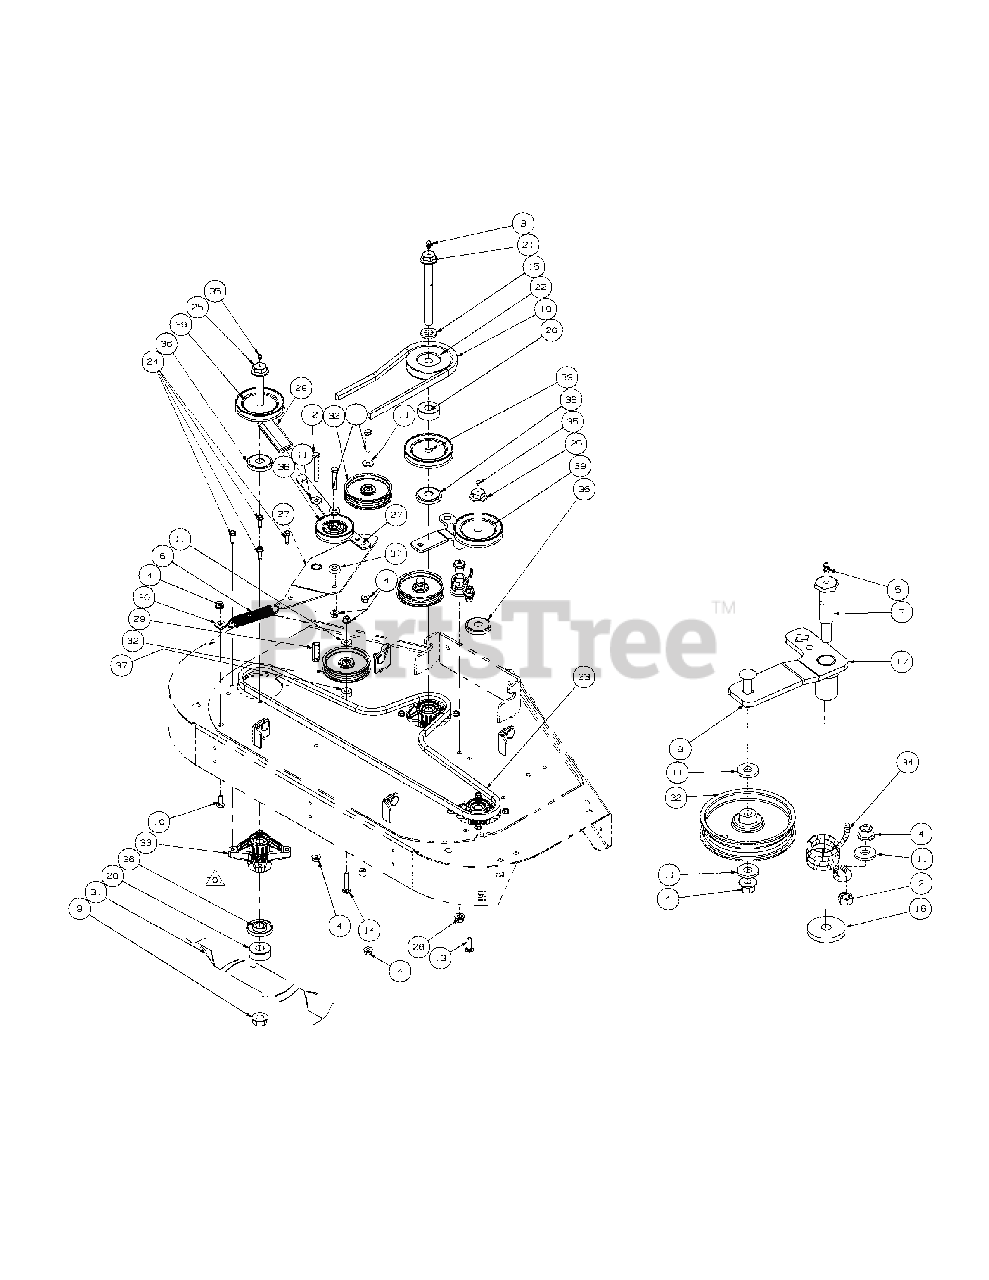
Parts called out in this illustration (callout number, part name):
1	Hex Cap Screw, 3/8-16 x 2.00
2	Hex Nut 3/8-16
3	Grease Fitting, 90°
4	Hex Nut, 3/8-16 Flange Lock
5	Grease Fitting, 1/4-28 x 3/16
6	Extension Spring, 1.0 OD x 5.00
7	Shoulder Screw, 7/16-14
8	Hex Carriage Screw, 3/8-16, 1.75
9	Hex Flange Nut, 3/4-16
10	Carriage Bolt, 3/8-16 x 1.00
11	Flat Washer, .406 ID x 1.0 OD x .105
12	Hex Cap Screw 3/8-16 x 2.75
13	Carraige Screw, 3/8-16 x 1.25
14	Carriage Bolt, 3/8-16 x 2.00
15	Spacer, .812 ID x .218
16	Flat Washer, 7/16 ID x 1.75 OD
17	Idler Arm Assembly, Deck Spindle includes:
18	Spacer, .625 OD x .385 ID x 1/2
19	Belt Drive
20	Spacer .760 ID x 2.00 OD x 0.790
21	Spindle Bolt, 3/4-16 x 7.155
22	V-Pulley 4.25 OD Casting
23	V-Belt, A-Section
24	Self Tapping Screw 5/16-18 x 1.00
25	Spindle Bolt 3/4-16 x 5.37
26	Nut, 7/16-20, FlangeLock
27	Idler Arm Assembly, Double, includes:
28	Spacer, .39 ID x .625 OD x 1.875
29	Grip, 1.0 x 3.2 x .25
30	Tension Spring Bracket
32	Flat Pulley
33	Spindle Assembly
34	Idler Torsion Spring
35	Grease Fitting
36	Spindle Spacer
37	Spacer .406 ID x 1.0 OD
38	V-Pulley, 3.5 OD
